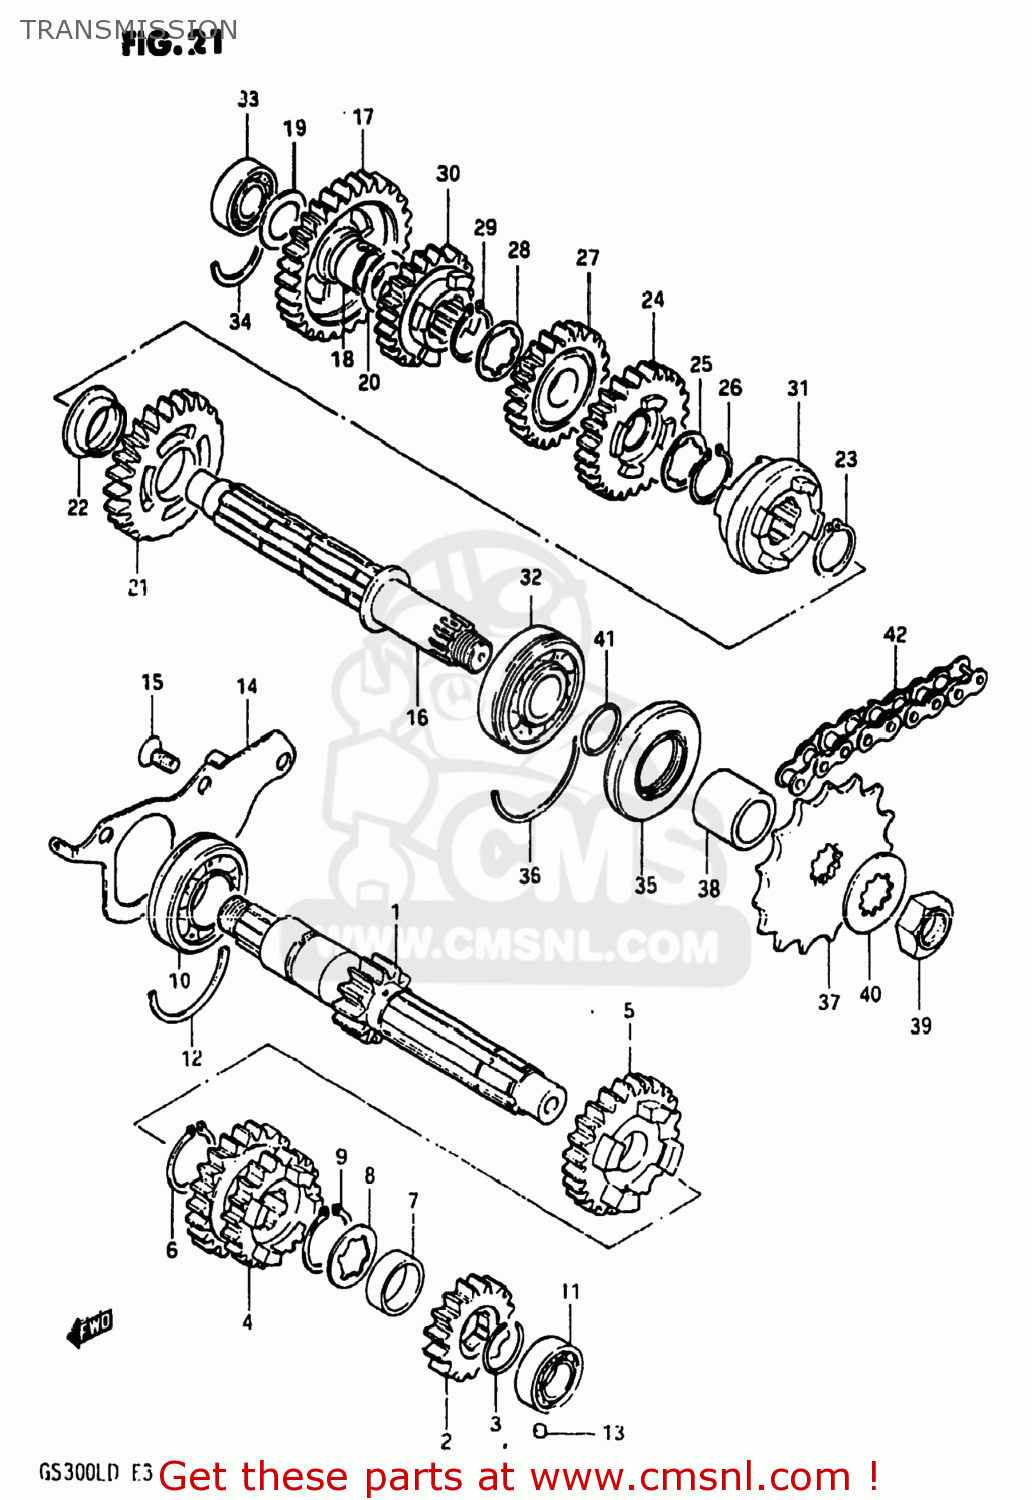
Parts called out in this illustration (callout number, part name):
1	SHAFT,COUNTER
2	GEAR,SECOND DRIVE
3	CIRCLIP
4	GEAR,THIRD/FOURTH DRIVE
5	GEAR,FIFTH DRIVE
6	CIRCLIP
7	SPACER
8	WASHER,LOCK
9	CIRCLIP
10	BEARING
11	ROLLER BEARING (17X31X1
12	C RING
13	PIN
14	RETAINER,BEARING
15	SCREW
16	SHAFT,DRIVE
17	GEAR,FIRST DRIVEN
18	BUSHING
19	WASHER,THRUST
20	WASHER,THRUST
21	GEAR,SECOND DRIVEN
22	BUSH
23	CIRCLIP
24	GEAR,THIRD DRIVEN
25	WASHER,LOCK
26	CIRCLIP
27	GEAR,FOURTH DRIVEN
28	WASHER,LOCK
29	CIRCLIP
30	GEAR,FIFTH DRIVEN
32	BEARING
33	BEARING, RH
34	C RING
35	SEAL,OIL(28X52X11.5)
36	C RING
37	SPROCKET,ENGINE(NT:15)
38	SPACER (20X28X25.2)
39	NUT
40	WASHER,LOCK
41	O RING(D:1,ID:19.5)
42	CHAIN ASSEMBLY,DRIVE
